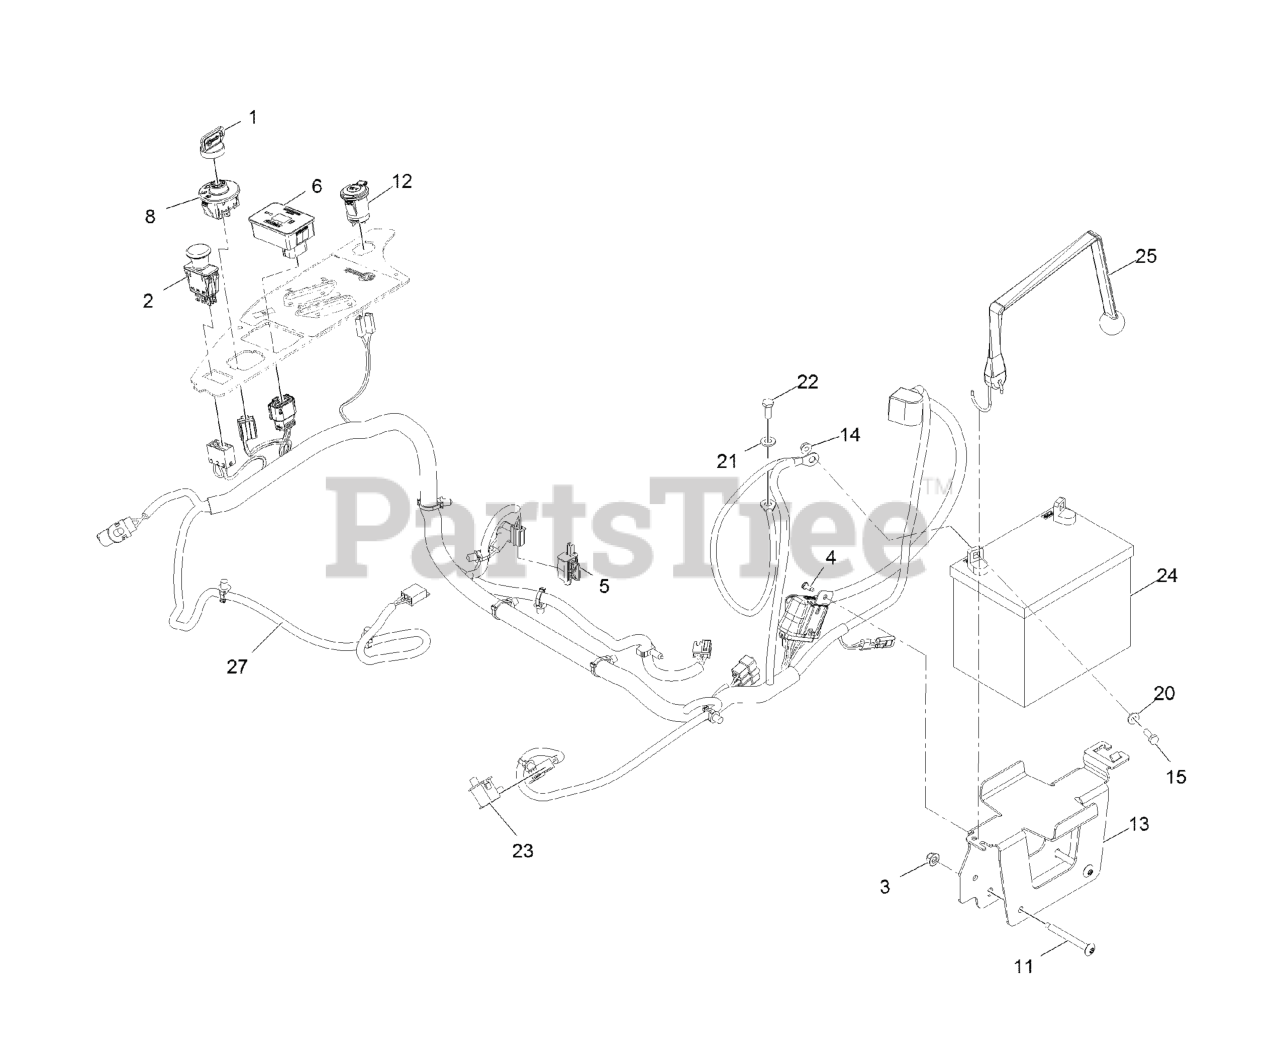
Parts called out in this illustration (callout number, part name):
1	KEYS-IGNITION (SPARE PAIR
1	KEY-IGNITION
2	SWITCH-PTO
3	NUT-HF, NI
4	SCREW-FORMING, THREAD
6	MODULE ASM
8	SWITCH-IGNITION
11	SCREW-TORX
12	PORT-POWER, 12V
13	TRAY-BATTERY
15	SCREW-HH
20	WASHER-FLAT
21	WASHER-PLAIN
22	SCREW-HH
23	SWITCH-BAIL
24	Battery
25	STRAP-BUNGEE
27	HARNESS - WIRING
